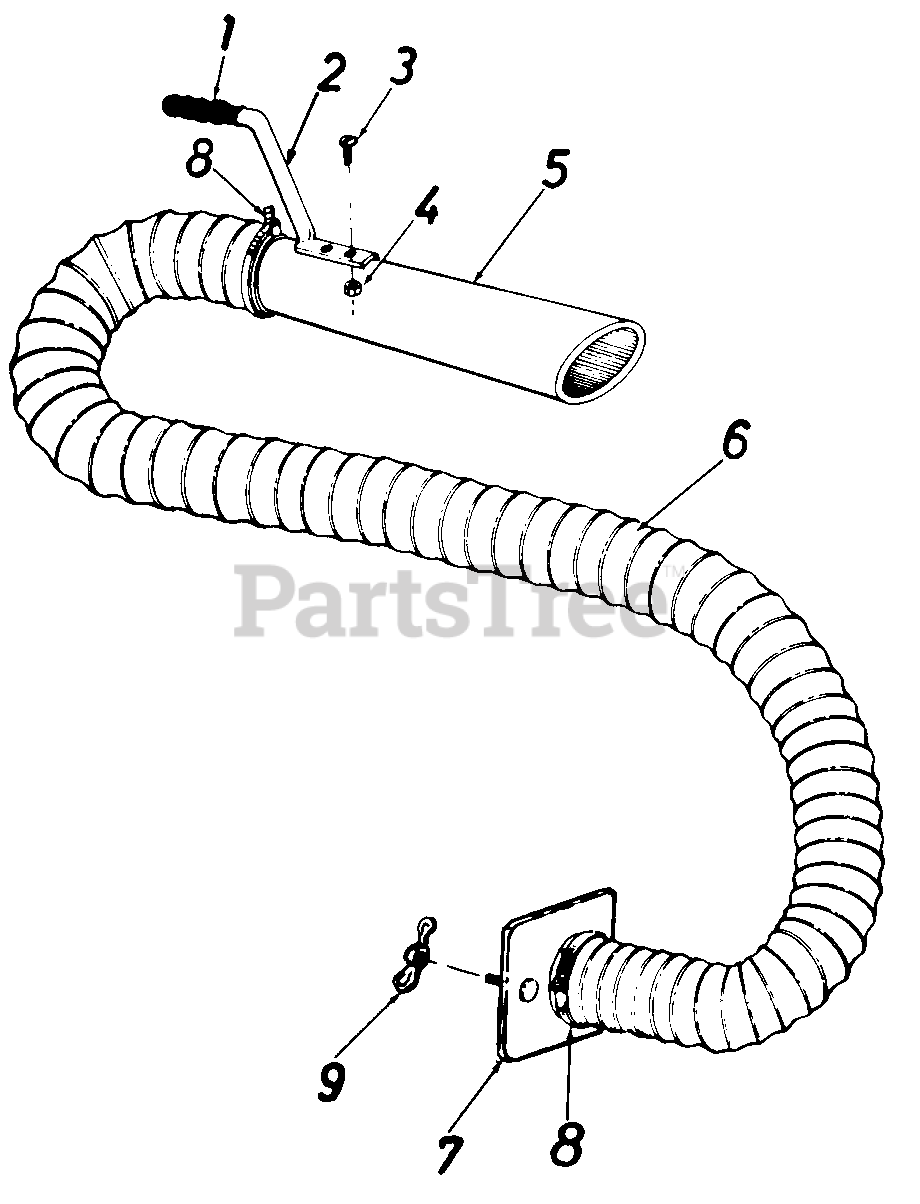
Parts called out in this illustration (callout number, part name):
1	Handle Grip
2	Handle
3	Truss Sems Scr. 10-24 x 1/2" Lg.*
4	Hex Nut 10-24 Thd.*
5	Hose Nozzle
6	Flex ible Hose 4" Dia. x 10' Lg.
7	Hose Adapter Plate
8	Hose Clamp-For 4" Dia. Hose
9	Wing Nut 1/4-20 Thd.
